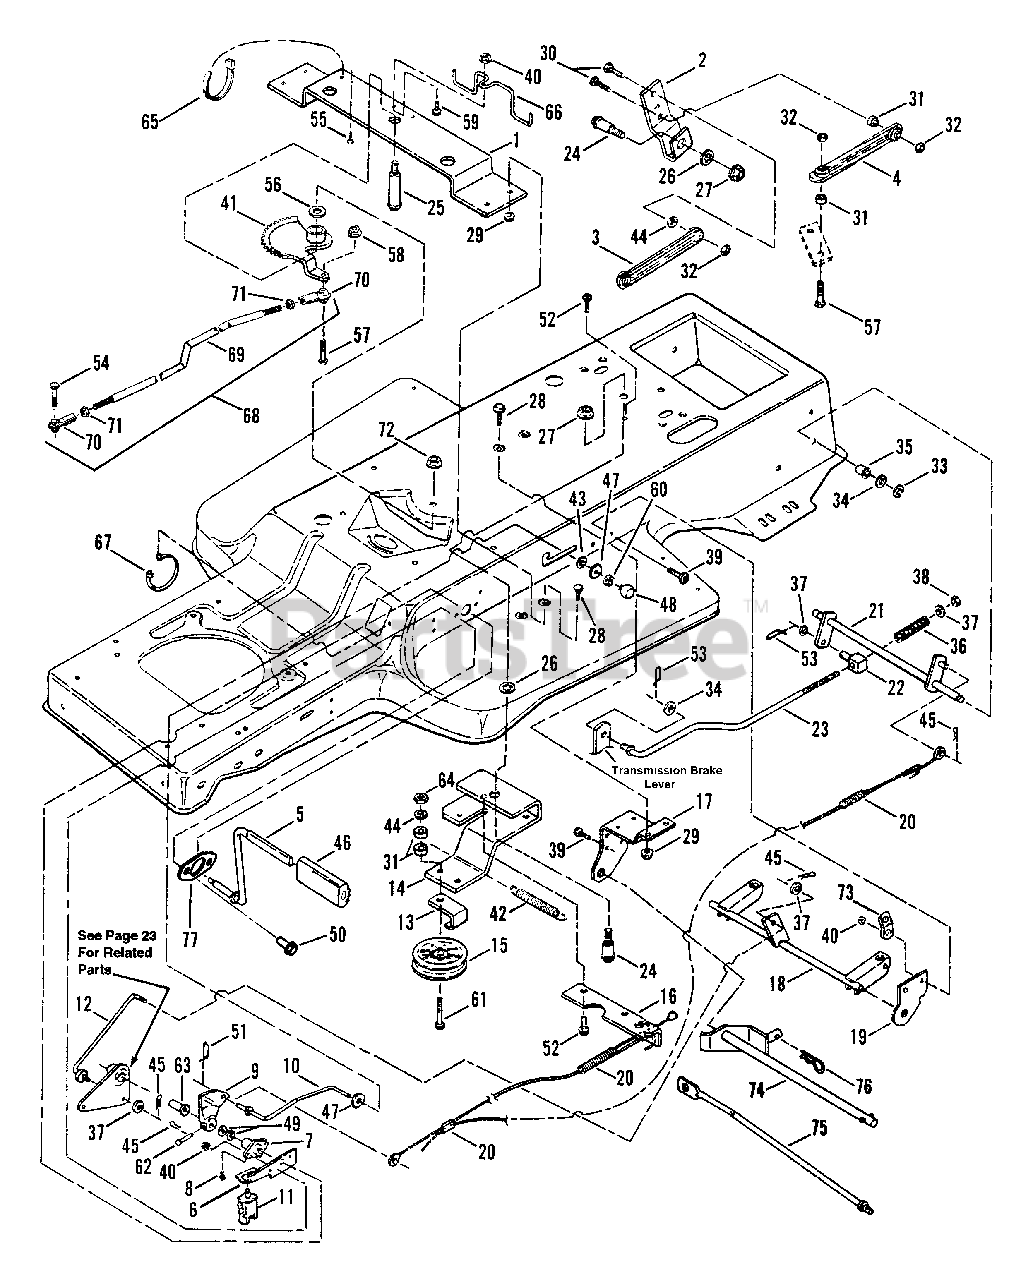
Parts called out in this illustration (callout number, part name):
1	BRACE, Sector Gear
2	BELLCRANK, Shift Lever
3	LINK, Shift Lever
4	LINK, Shift Lever (Twisted)
5	PEDAL, Park Brake
6	BRACKET, Brake Switch
7	ASSEMBLY, Foot Shaft Pivot
8	FITTING, Lube
9	ASSEMBLY, Clutch/Brake Arm
10	LATCH, Park Brake
11	SWITCH
12	ROD, Lift Link
13	GUIDE, Pulley
14	ARM, Idler (Traction Drive)
15	PULLEY
16	EXTENSION, Idler Arm
17	BRACKET, Rear Lift/PTO Lever
18	WELDMENT, Rear Lift
19	BRACKET, Deck Hang Pivot
20	ASSEMBLY, Clutch Brake Cable
21	WELDMENT, Brake Pivot
22	SWIVEL, Brake Link
23	ROD, Brake
24	BOLT, 1/2-13 x 2" Shoulder
25	BOLT, 1/2-13 x 3 7/8" Shoulder
26	WASHER, 1/2 Internal Tooth Lock
27	NUT, 1/2-13 Hex Flange Lock
28	BOLT, 1/4-20 x 5/8" Carriage
29	NUT, 1/4-20 Hex Flange Lock
30	SCREW, 3/8-16 x 1 1/4" Hex Head Cap
31	SPACER
32	NUT, 3/8-16 Hex Center Lock
33	RING, 1/2" External Retaining
34	WASHER, 1/2 Flat
35	BEARING, Nylon
36	SPRING, Brake
37	WASHER, 3/8" Flat
38	NUT, 3/8-16 Hex Nyloc
39	SCREW, 5/16-18 x 5/8" Truss Head (Torx)
40	NUT, 5/16-18 Hex Flange Lock
41	ASSEMBLY, Sector Gear
42	SPRING, Idler
43	RETAINER, 5/16 Bolt
44	WASHER, 3/8 Split Lock
45	HAIRPIN, 3/32 x 1 1/2"
46	PAD, Pedal
47	WASHER, 5/16 Nylon
48	KNOB, Push/Pull
49	WASHER, 5/8 Flat
50	SCREW, 5/16-18 x 7/8" Truss Head (Torx)
51	COTTER-PIN, 3/64 x 1 7/32" (Self-Locking)
52	SCREW, 5/16-18 x 5/8" Self-Tapping
53	COTTER-PIN, 1/16" x 1.42" Self-Locking
54	SCREW, 3/8-24 x 1 1/4" Hex Head Cap
55	SCREW, #10-24 x 1/2" Hex Washer Self-Tap (Torx)
56	WASHER, 3/4 Thrust
57	SCREW, 3/8-16 x 1 1/2" Hex Head Cap
58	NUT, 3/8-16 Hex Flange Lock
59	BOLT, 5/16-18 x 3/4" Hex Flange Lock
60	RING, Tolerance
61	SCREW, 3/8-16 x 2 1/4" Hex Head Cap
62	PIN, 3/16 x 1 1/2" Clevis
63	BEARING, Flange
64	NUT, 3/8-16 Hex
65	TIE, Cable
66	GUIDE, Drive Belt
67	TIE, Wire
68	ASSEMBLY, Drag Link
69	LINK, Drag
70	BALL JOINT, 3/8-24
71	NUT, 3/8-24 Hex Jam
72	NUT, 1/2-13 Hex Center Lock
73	CLIP, Spring
74	ASSEMBLY, Stabilizer Shaft
75	BAR, Stabilizing
76	HAIRPIN, 5/64 x 1 3/16"
77	WASHER, Pivot-Stiffener
